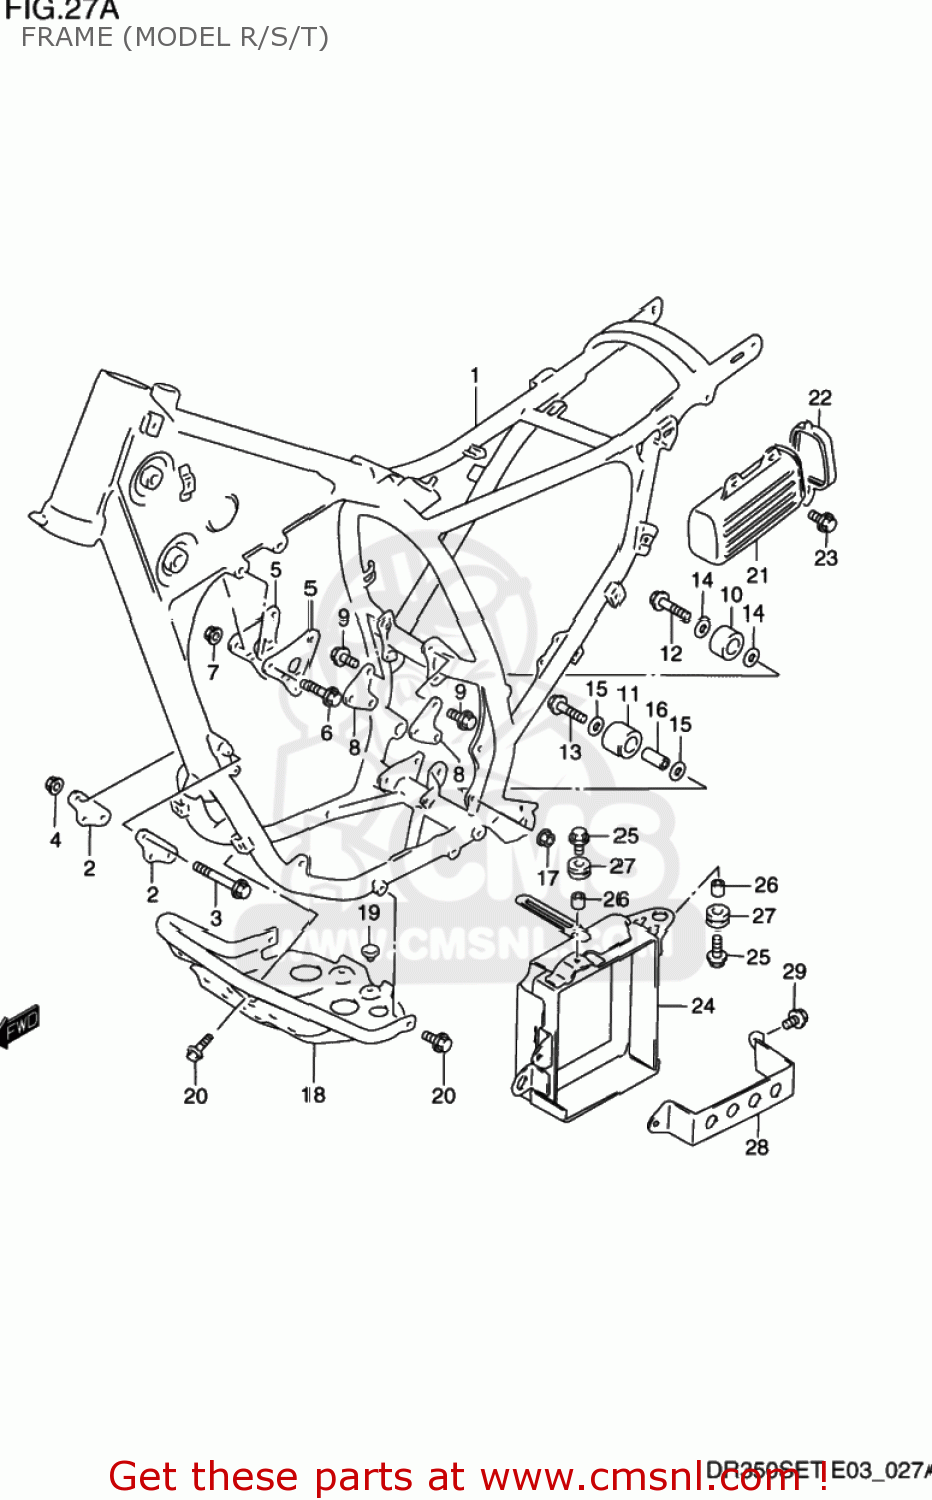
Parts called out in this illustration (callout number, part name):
1	FRAME
2	PLATE,ENGINE MOUNT FR
3	BOLT(8X85)
4	NUT
5	PLATE,ENGINE MOUNT UPR
6	BOLT(8X70)
7	NUT
8	PLATE,ENGINE MOUNTING,REAR
9	BOLT(8X16)
10	ROLLER,CHAIN
11	ROLLER,CHAIN CONTROL
12	BOLT(8X38)
13	BOLT 8X45
14	WASHER
15	WASHER
16	SPACER (8.6X13.8X28)
17	NUT
18	PROTECTOR,ENGINE(SILVER)
19	CUSHION
20	BOLT
21	HOLDER,TOOL
22	CAP,TOOL HOLDER
23	BOLT 6X16
24	HOLDER,BATTERY
25	BOLT(6X20)
26	SPACER (6.8X10X9)
27	CUSHION
28	COVER,BATTERY HOLDER
29	SCREW(6X10)
